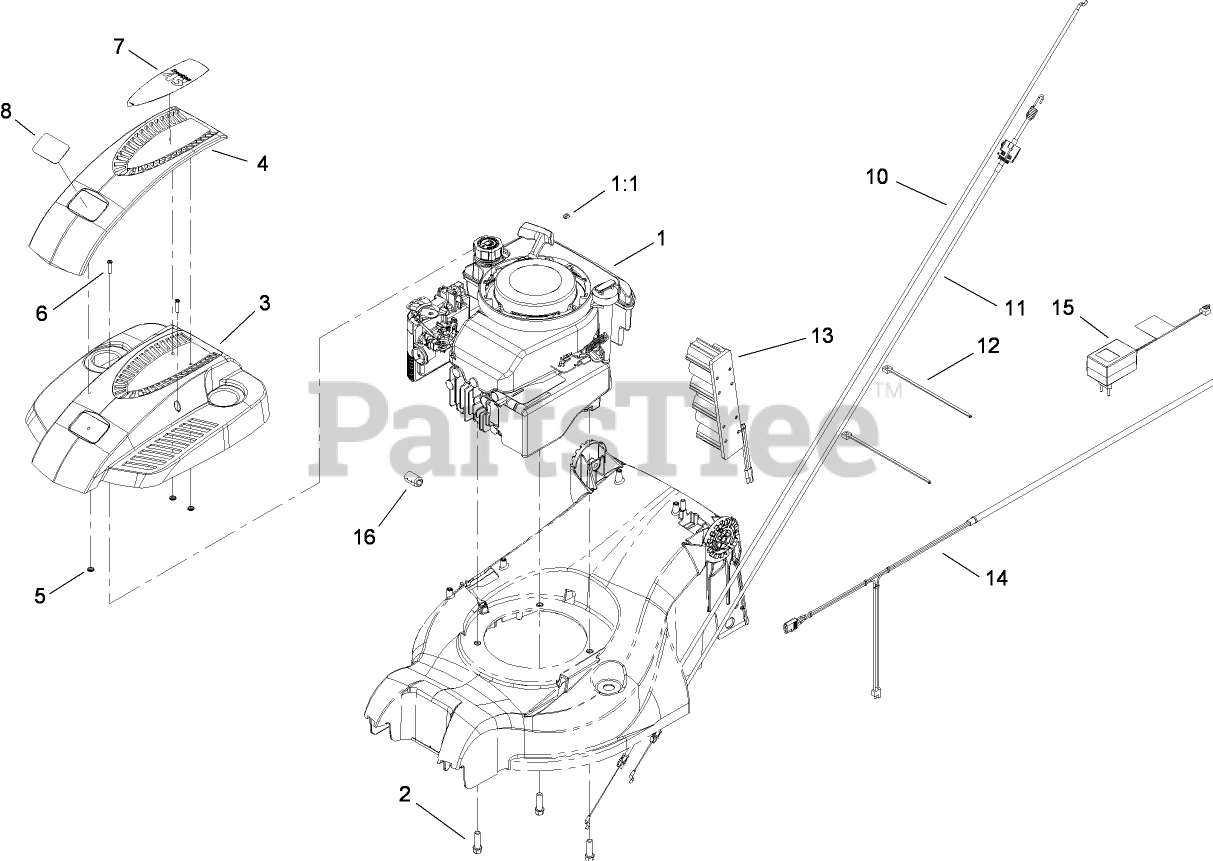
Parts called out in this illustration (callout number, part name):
1	Loose Parts Package
1:1	STOP-ROPE
2	SCREW-TAPTITE
3	SHROUD-ENGINE
4	COVER-SHROUD
5	CLIP-PUSH
6	SCREW-PPH
12	TIE-CABLE
13	BATTERY-WET
14	HARNESS-WIRING
15	CHARGER-EUROPEAN, 12V DC
16	FERRITE-SNAP ON
